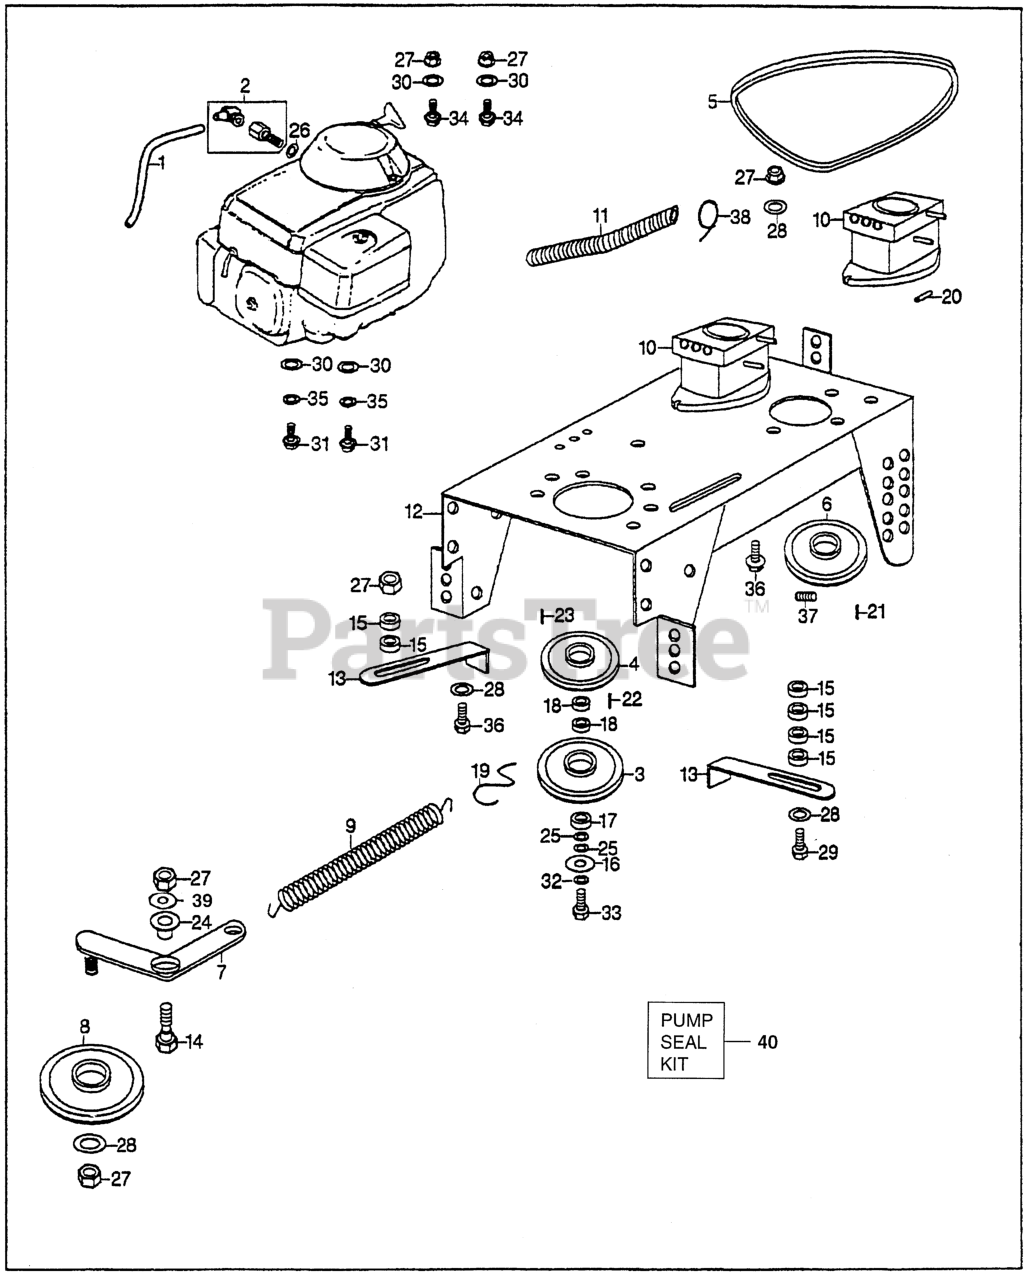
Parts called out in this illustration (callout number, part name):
1	TUBE, OIL DRAIN
2	VALVE, OIL SHUT-OFF
3	PULLEY KIT, ENGINE
4	PULLEY KIT, ENGINE
5	V-BELT, ENGINE PUMP
7	BELLCRANK, IDLER
8	PULLEY, IDLER
9	SPRING, TENSIONER
10	PUMP ASSY., HYDRAULIC (SEE KIT 25010-VE4-000--END OF BLOCK)
11	COVER, HOSE
12	BED, ENGINE
13	GUIDE A, BELT
14	BOLT A, SHOULDER
16	WASHER, SPECIAL
17	SPACER (7/16")
18	SPACER (1/4")
19	CLIP, SPRING
20	PIN, TAPERED
21	KEY, SQUARE (5X5X28)
22	KEY, SQUARE (1/4"X1/4"X1")
23	KEY, TAPER
24	BUSHING, SNAP
25	BUSHING (1/2")
26	WASHER, DRAIN PLUG (20MM)
39	WASHER (5/16")
40	SEAL KIT, PUMP
